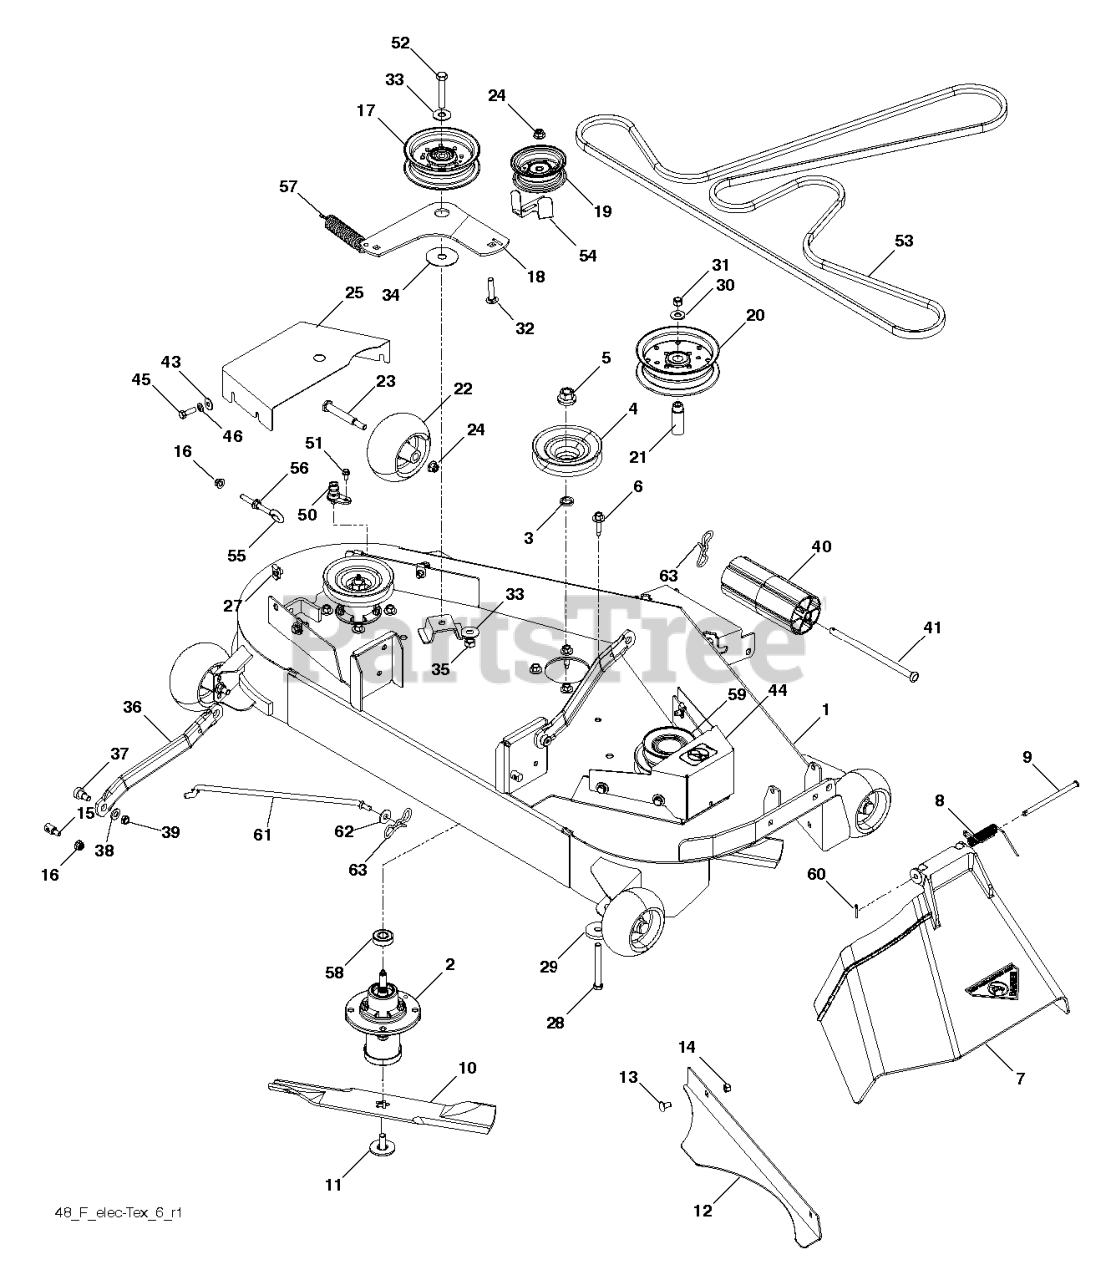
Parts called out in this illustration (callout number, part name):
1	DECK RAW WLDT 48"
2	MANDREL.DECK.ASSEMBLY
3	WASHER.SPACER.MANDREL
4	PULLEY.DRIVEN.DECK.48'
5	NUT.FLANGE.LOCK.TOP
6	SCREW, WASHER HEAD
7	DISCHARGE CHUTE 48"
8	SPRING - TORSION
9	PIN-CLEVIS 5/16 DIA X 5.19 ZD
10	BLADE, 16-1/4"
11	BOLT.WASHER.ASM.7/16-2
12	PLATE.CONFINEMENT.48"
13	BOLT.CARR.5/16-18X5/8.SHORT
14	NUT.71038.31-18.HEX.NYLOCK
15	STUD.FASTNER.W/ANTI-ROTATE
16	NUT.LOCK.FLANGE.7/16
17	PULLEY.IDLER.MWR.STATI.LH
18	ARM, IDLER, BLK
19	PULLEY.IDLER.FLAT
20	PULLEY, IDLER
21	BUSHING, IDLER
22	GAUGE WHEEL
23	BOLT.SHOULDER.3/8-16X3-5/8.
24	NUT 3/8-16 HEX FLG NYLOC ZD
25	SHIELD.BELT.LH.ORANGE
27	U-CLIP 5/16-18 NUT RETAINER
28	SCREW
29	SPINDLE WASHER
30	RP WASHER 3/8 FLAT
31	NUT 3/8-16 NYLOC
32	RHSNB 3/8-16X1-3/4
33	WASHER 7/16 FLAT ZD
35	NUT.LOCK.FLANGE.7/16
36	ARM.SUSPENSION.MOWER
37	SB 3/8-16 X 3/8 SKT HD ZD
38	WASHER
39	NUT HEX 3/8-16 NYLON, THIN
40	NOSE ROLLER 48"
41	ROD.ROLLER.NOSE.NARROW.48"
43	WASHER.5/16.FLAT.STE.STD.
45	BOLT.FIN.HEX.5/16-18UNC X 1.00
46	WASHER.LOCK.HVY.HLCL.SPR.5/16
50	PORT.WASHOUT
51	BOLT 1/4-20 X 1/2 HWST
52	BOLT.HEX.7/16-14
53	BELT, 135" EL
54	BELT GAURD
55	EYE BOLT 5/16 X 3.50
56	NUT LOCK HEX FLANGE 5/16-18
58	BEARING, BALL
59	RP PULLEY, COLLECTION 48
60	RETAINER CLIP
61	ROD.ANTI.SWAY.48/54"K4
62	WASHER
63	PIN.COTTER.5/16.BOW TI
